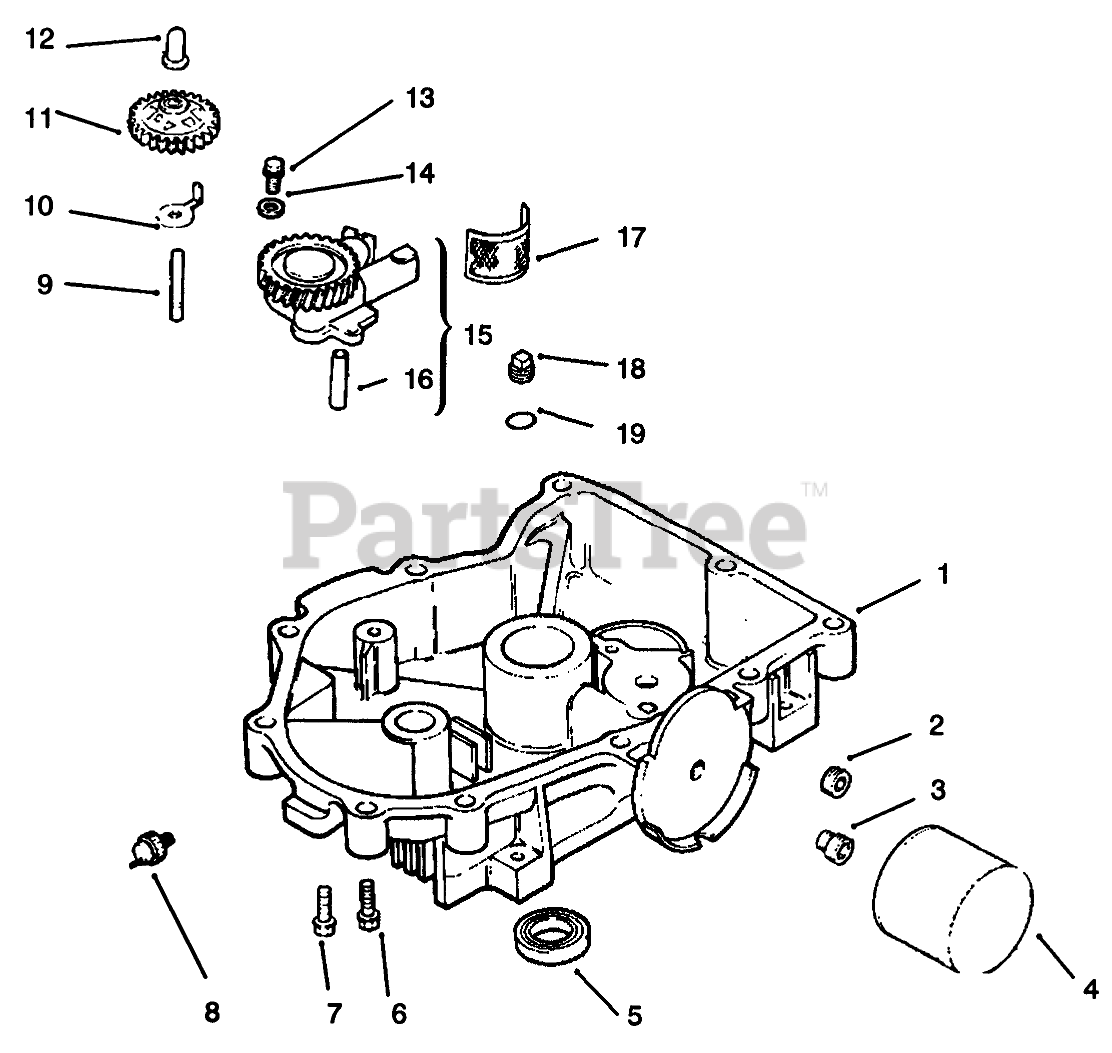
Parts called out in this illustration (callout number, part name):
1	Oil Pan
2	Plug-Hex
3	Nipple-Oil Filter
4	Filter-Oil
5	Seal-Oil
6	Screw M8 x 1.25 x 45
8	Switch-Oil Pressure
9	Shaft-Govenor Gear
10	Tab-Locking
11	Governor Gear ASM
12	Pin-Governor
13	Screw-Valve Cover
14	Washer-Governor
15	Oil Pump ASM INC 16
16	Tube-Oil Pickup
17	Screen-Oil Pickup
18	Plug
